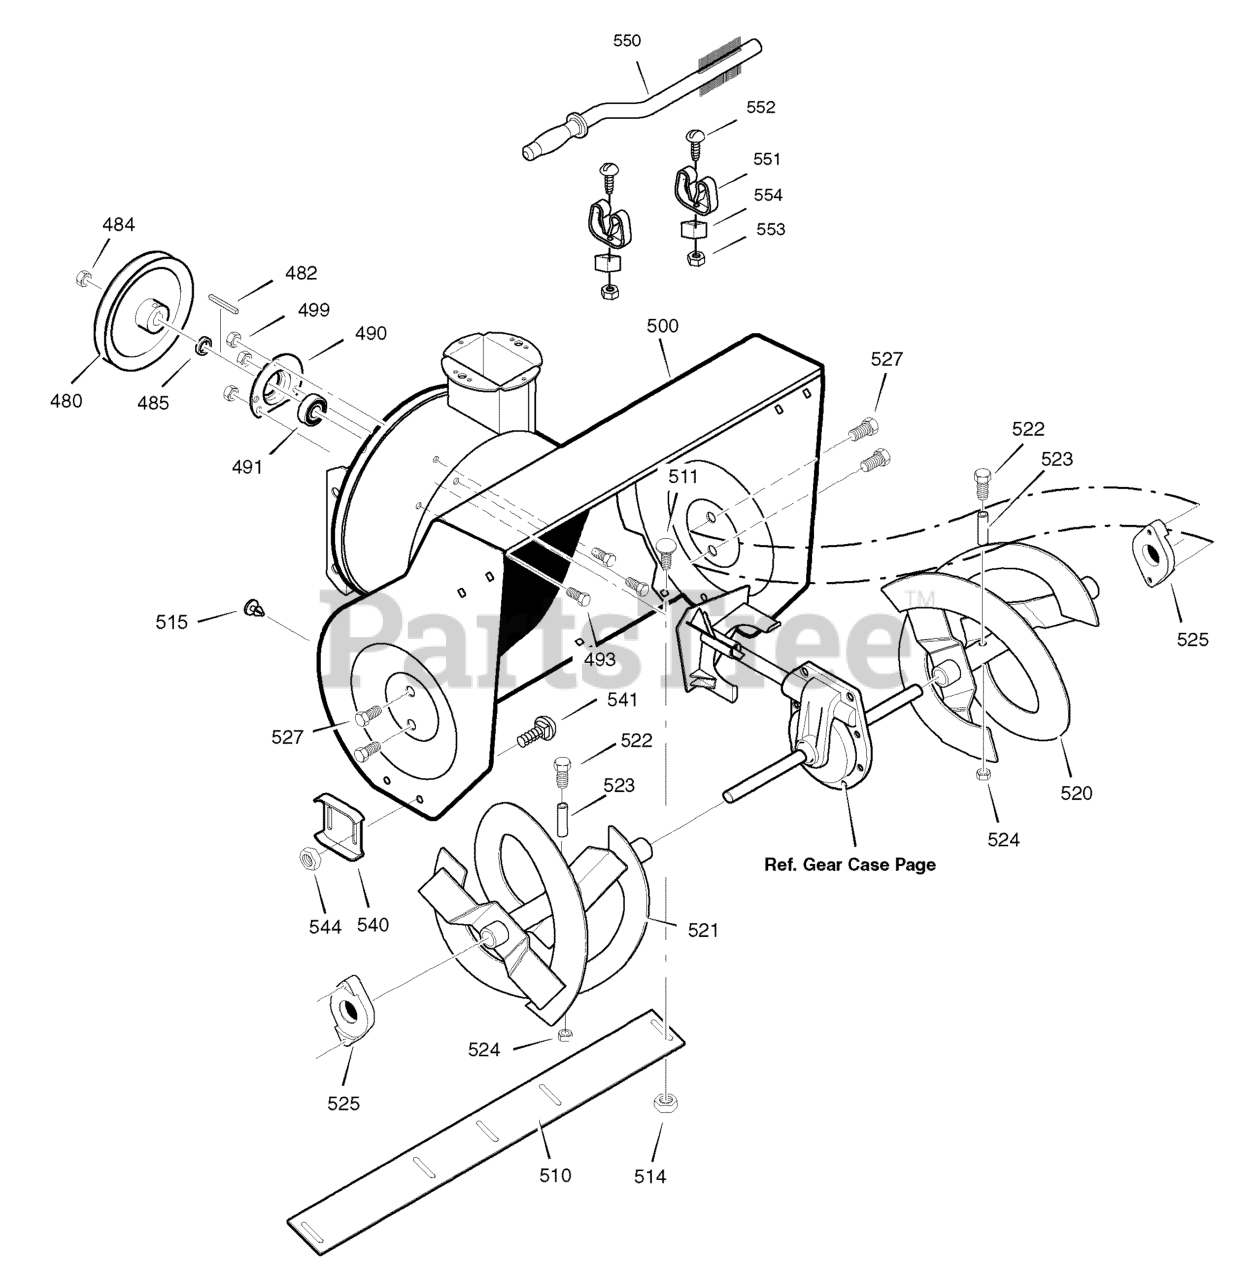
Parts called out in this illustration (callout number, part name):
480	PULLEY, 4L 8.40 OD.
482	KEY, SQUARE 3/16 X 3/4
484	NUT, .50-20 HEXWDFLLK
485	SPACER, FRICTION PULLEY
490	RETAINER, BALL BEARING
491	BEARING, BALL
493	BOLT, HEX 5/16-18 X .62
499	NUT, 5/16-18 HEXWDFLLK
500	HOUSING, ASSEMBLY
510	BLADE, SCRAPER
511	BOLT, 5/16-18 X .75
514	NUT, 5/16- 18
515	PLUG, PANEL
520	AUGER, ASSEMBLY, LH
521	AUGER, ASSEMBLY, RH
522	SCREW, 1/4-20 X 1.75
523	SPACER, SLEEVE
524	NUT, 1/4-20
525	BEARING, FLANGE
527	SCREW, 5/16-18 x 0.75
540	SKID, HEIGHT ADJUST
541	BOLT, 5/16-18 X 50
544	NUT, 5/16-18
550	BRUSH, CLEANOUT
551	CLIP, RETAINER
552	SCREW
553	NUT
